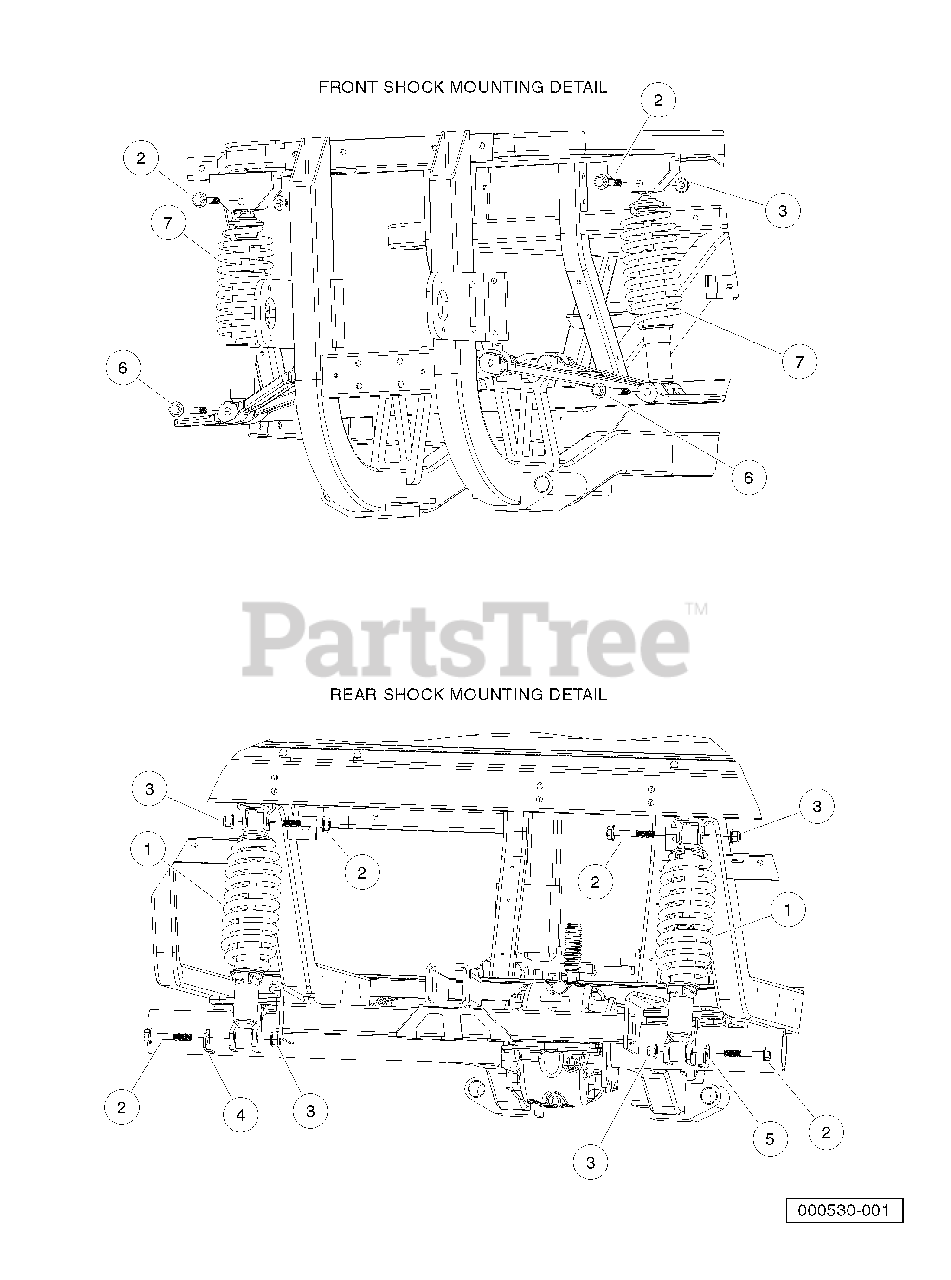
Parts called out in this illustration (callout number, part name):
1	Shock, Coil Over Rear
2	Bolt, Flange Head, M12 X 1.75 X 70
3	Nut Flg, M12x1.75, Nylon Gr 10
4	Brkt, Line, Hyd, Shk Mnt, Drv
5	Brkt, Line, Hyd, Shk Mnt, Pass
6	Bolt Flg, M12x1.75x100, Patch
7	Asm, Coil & Shock, Frt
